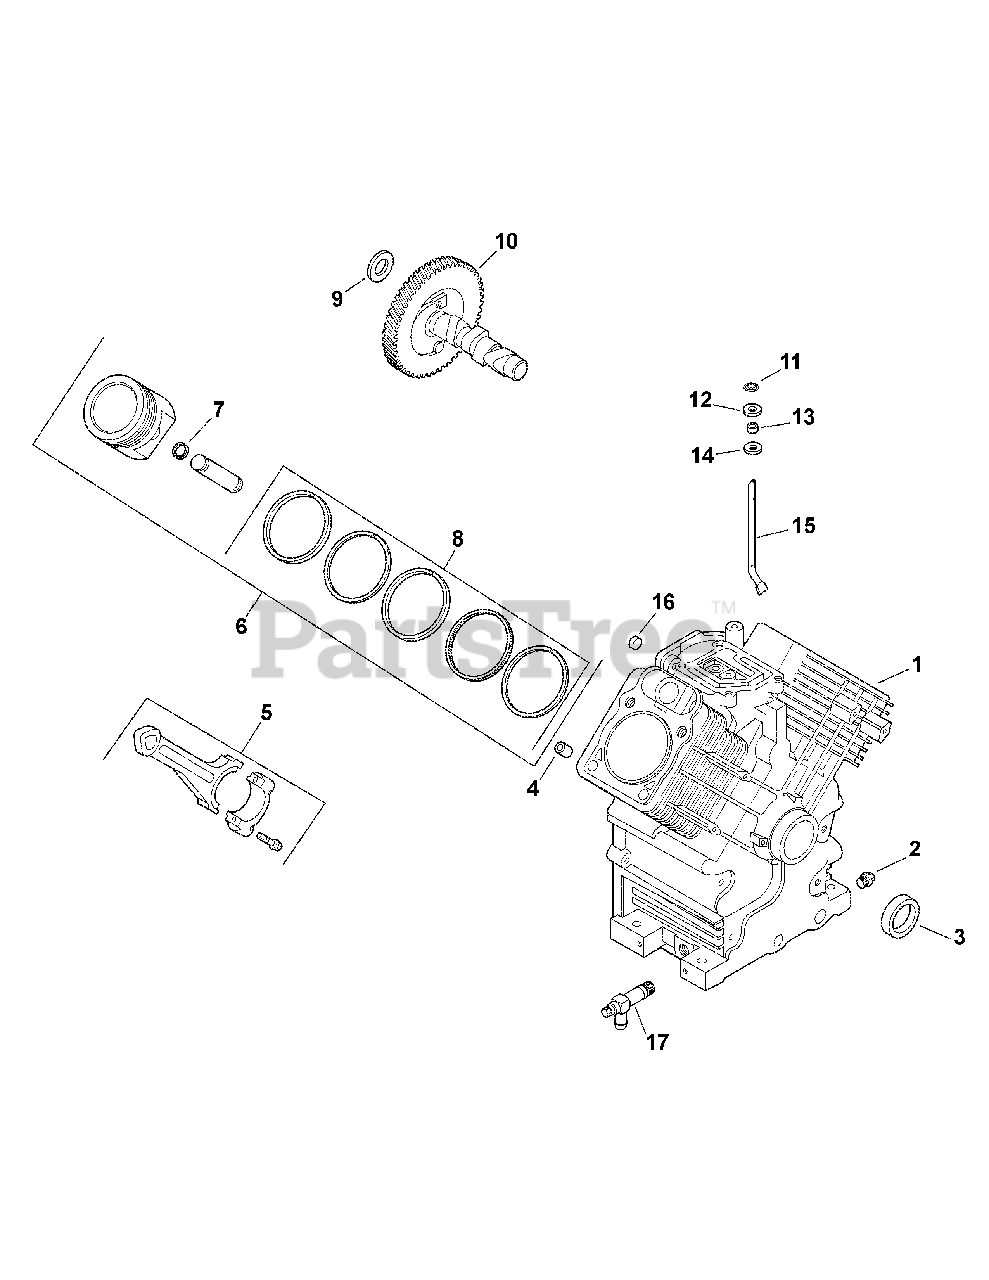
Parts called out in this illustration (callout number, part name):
1	Crankcase
2	Plug, sq. head 3/8"
3	Seal, front oil
5	Connecting Rod (Std.)
5	Connecting Rod (.25)
6	Piston w/Ring Set (Std.)
6	Piston w/Ring Set (.08)
6	Piston w/Ring Set (.25)
6	Piston w/Ring Set (.50)
7	Retainer, piston pin
8	Ring Set (Std. & .08)
8	Ring Set (.25)
8	Ring Set (.50)
9	Shim, camshaft (A.R.) red
9	Shim, camshaft (A.R.) black
9	Shim, camshaft (A.R.) white
9	Shim, camshaft (A.R.) blue
9	Shim, camshaft - yellow
9	Shim, camshaft (A.R.) green
9	Shim, camshaft (A.R.) gray
10	Camshaft
11	Retainer, ring
12	Washer, plain 9 mm
13	Seal, governor cross shaft
14	Washer, plain 1/4"
15	Shaft, governor cross
17	Valve, oil drain
